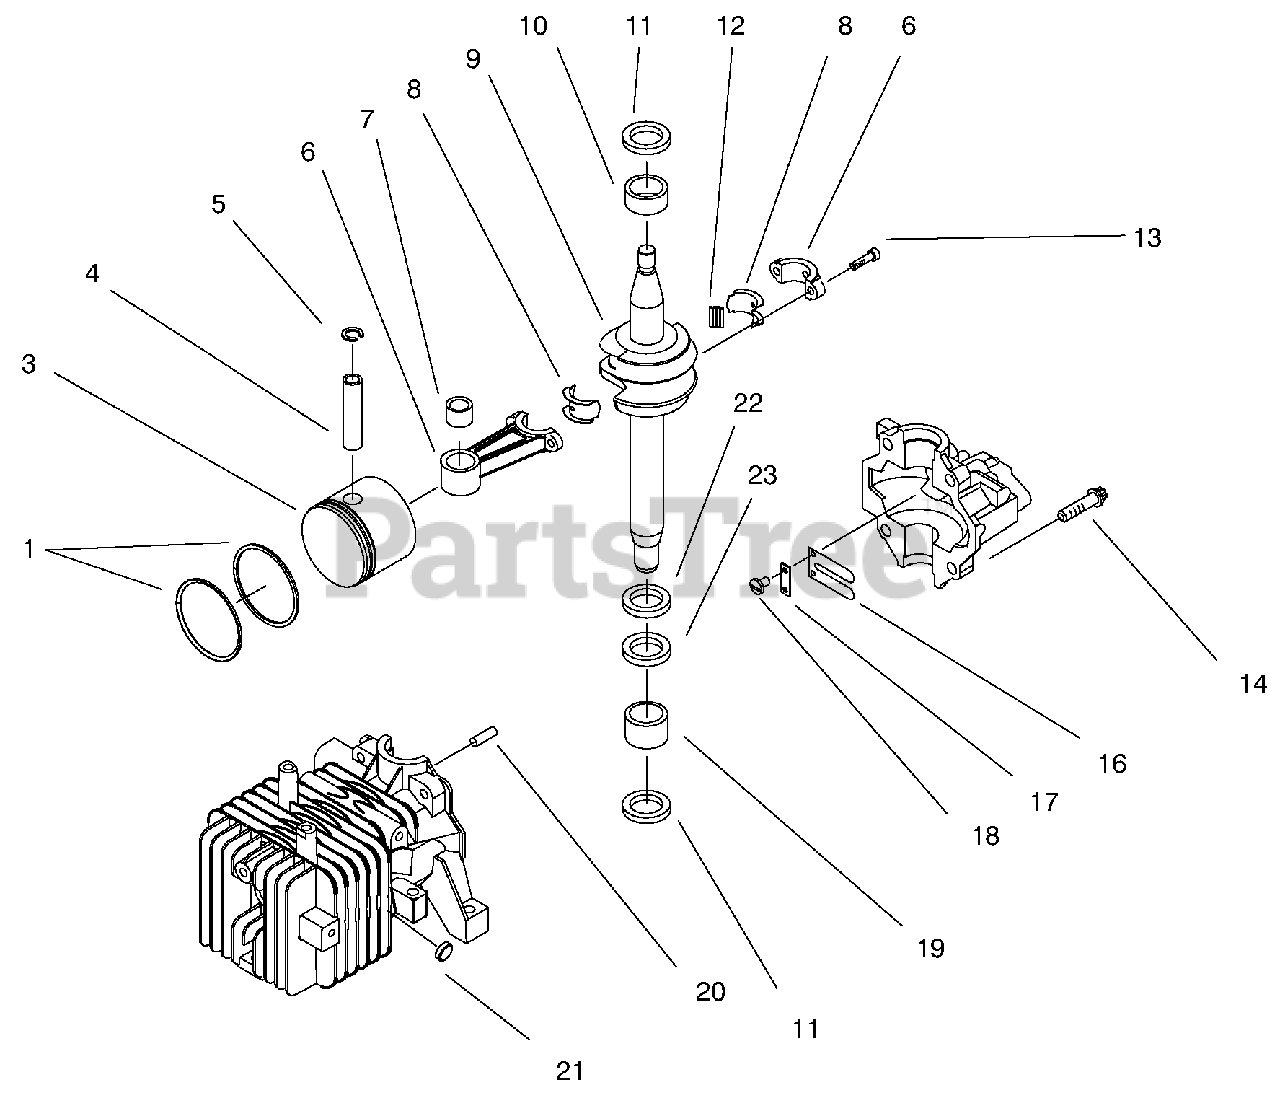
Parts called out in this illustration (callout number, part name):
1	Set-Ring
3	Piston & Ring Set
4	Pin-Wrist
5	Ring-Retaining
6	Connecting Rod Assembly (Incl. Ref. #6-8, 12, & 13)
8	Liner-Split (Set of 2)
9	Crankshaft
10	Bearing-Upper Main
11	Seal-Oil
12	Bearing-Needle
13	Screw-Hex. Hd.
14	Screw-Torx. Washer Hd.
16	Reed-Carburetor
17	Reed-Backup Plate
19	Bearing-Needle
21	Plug-Core
22	Bearing-Thrust
23	Washer-Thrust
